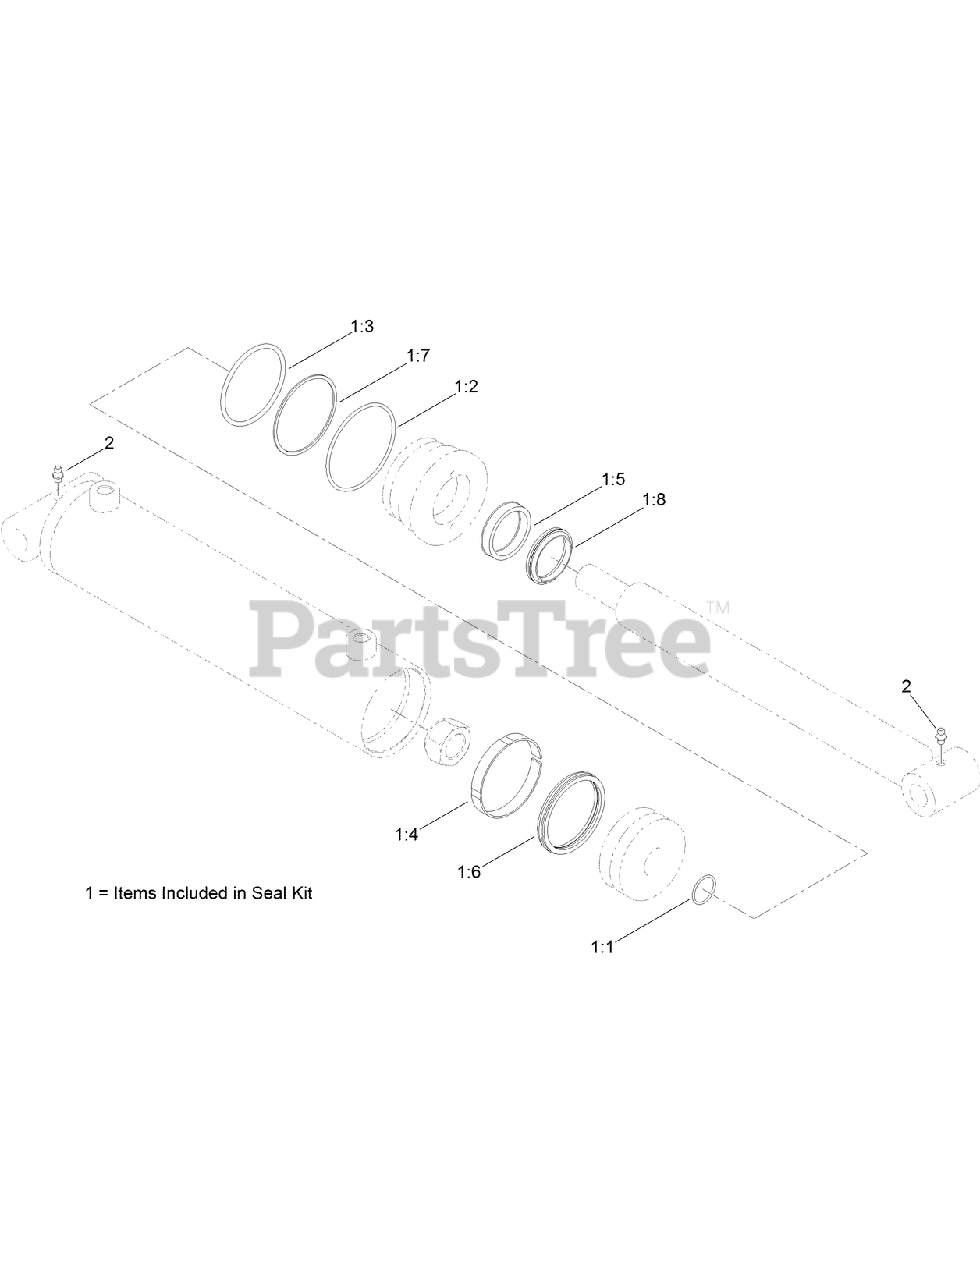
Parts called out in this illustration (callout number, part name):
1	SEAL KIT
1:1	O-RING
1:2	O-RING
1:3	O-RING
1:4	RING-PISTON BEARING
1:5	Seal-U Cup
1:6	SEAL-CROWN
1:7	Washer-Back Up
1:8	WIPER
2	FITTING-GREASE
